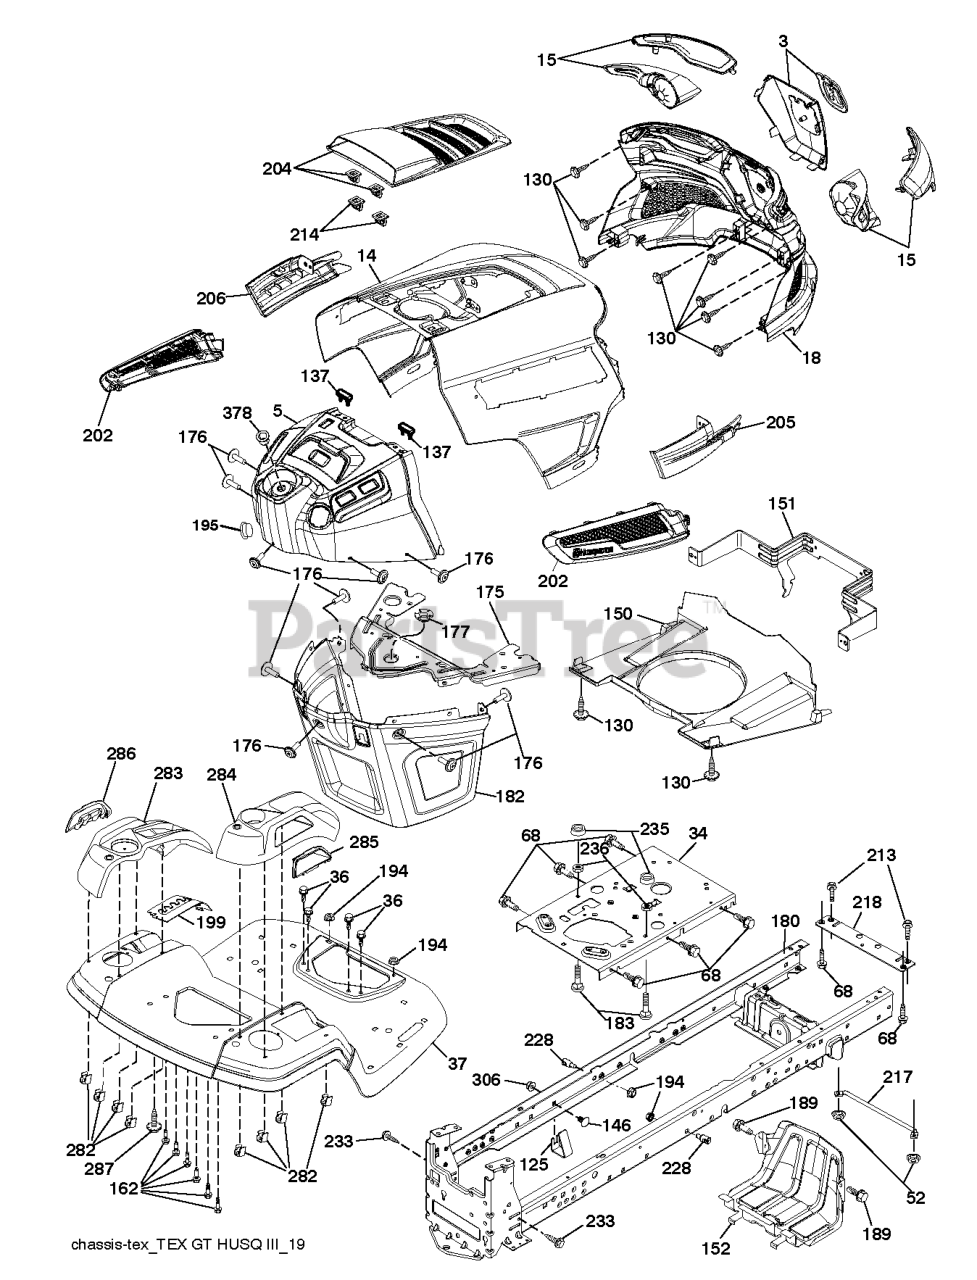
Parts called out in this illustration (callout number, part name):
14	HOOD.ASM.HUSQVARNA.GT.TEX.ORAN
15	Service Kit
34	PLATE.ENGINE.WELDED.CHASSIS
36	SCREW 5/16"
37	FENDER.TLT.FS.W/CUPHLD.ORANGE
125	CLIP.FUEL.LINE
137	BUMPER DASH
146	BOLT.RDHD.SHT.SQNK.3/8-16X5/8
150	AIR.DUCT.GTV.BLACK
151	BRACKET.PIVOT.HOOD.GT.HUSQ.II
152	SHIELD.BROWNING.PNT.GT.V2
175	PLATE.PNT.CROSSMEMBER.HUSQ/PRE
176	SCREW.#10-24X5/8.RN.QU
177	BUSHING STEERING
180	CHASSIS
182	DASH LOWER.HUSQ.PRED NO CRUISE
189	SCREW
195	PLUG.HOLE.DASH.LOWER.12V.BLK
199	PLATE.DECK.LIFT.HUSQ.LT
202	Vents
205	SIDE.TRIM.RH.GT.HUSQ.II
206	SIDE.TRIM.LH.GT.HUSQ.II.GRAY
213	SCREW HEXAGON HEAD SCREW 5/16-
214	CLIP.RETAINER.TINNER.
217	ROD.PIVOT.HOOD
218	X-PIECE.HOOD.STOP.NON/
228	STUD.W/"D"ANTI-ROTATION
233	BOLT.SHOULDER
236	NUT.CENTERLOCK.5/16-
282	CLIP.RETAINER.CONSOLE.LT.HUSQ
283	CONSOLE.ASM.LFT.RSF.HUSQ.LT
284	CONCOLE.CNTRL.PDL.HUSQ.LT.498
285	CONSOLE INSERT RH
286	CONSOLE.INSRT.LH.HUSQ.LT.BLACK
287	SCREW 1/4X20
306	NUT LOCK FLG 3/8-16 UNC
378	BUSHING FLANGE; PLASTIC
